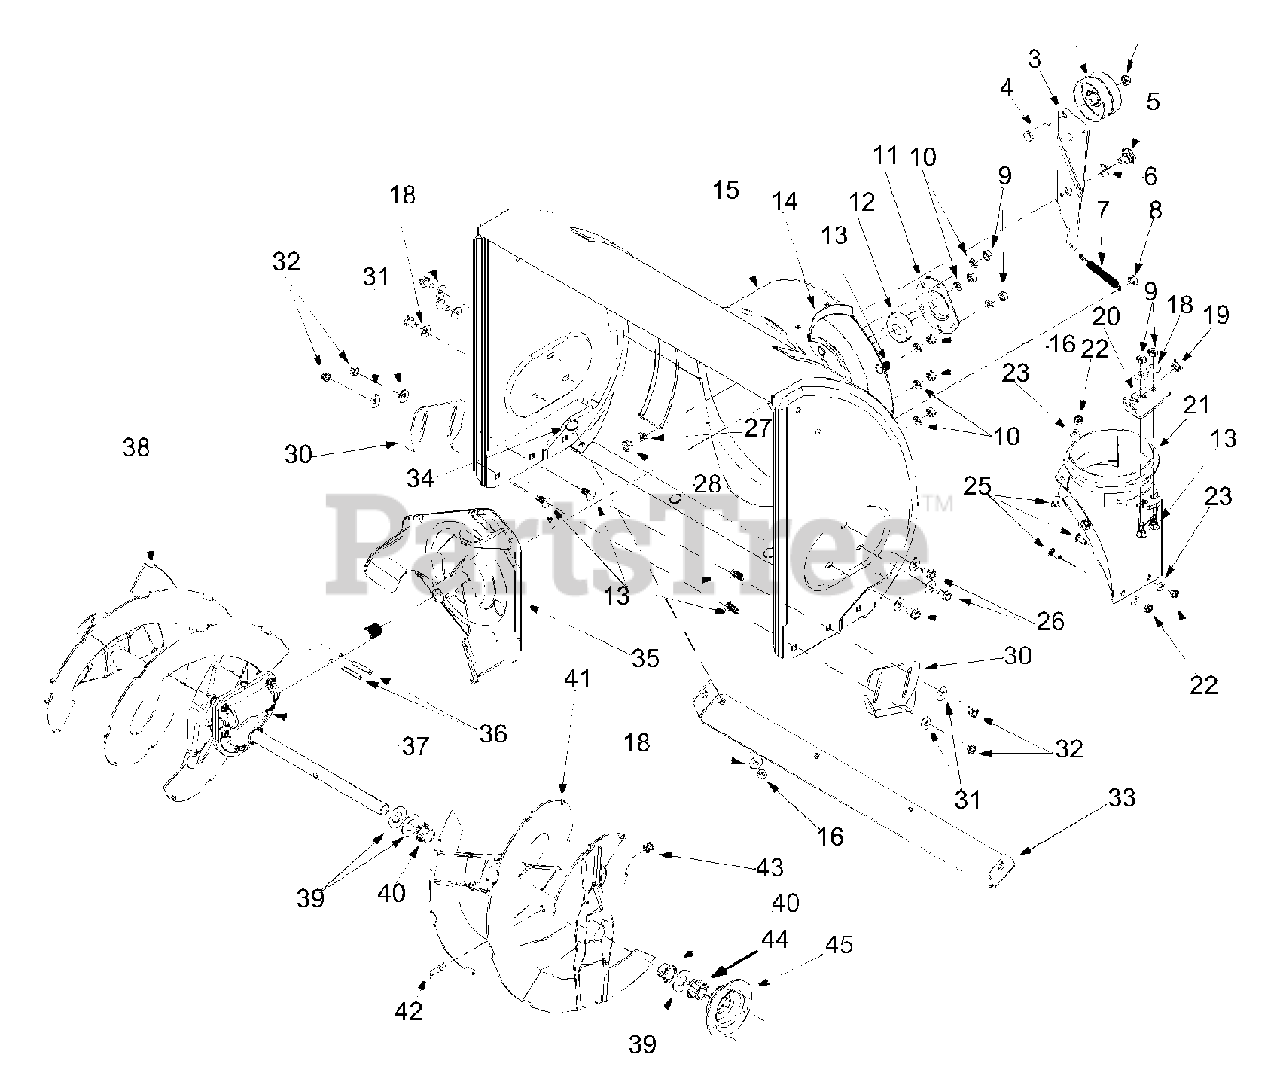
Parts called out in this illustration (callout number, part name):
1	Lock Jam Nut 3/8-24
2	Flat Idler
4	Hex Cap Screw 3/8-24 x 1.50
5	Shoulder Screw
6	Wave Washer
7	Extension Spring
8	Hex Nut 5/16-18
9	Hex Nut 5/16-18
10	Lock Washer 5/16
11	Housing
12	Ball Bearing
13	Carriage Bolt 5/16-18 x .75
18	Bell Washer
19	Bushing
21	Chute Adapter
22	Hex Lock Nut 1/4-20
23	Flat Washer
25	Carriage Screw 1/4-20 x .75
26	Hex Washer TT Screw 5/16-18
27	Lock Washer 3/8
28	Hex Nut 3/8-16
31	Bell Washer
32	Hex Nut 5/16-18
34	Carriage Bolt 5/16-18 x .62
37	24" Gear Assembly
39	Flat Washer
40	Flange Bushing
42	Shear Bolt 5/16-18 x 1.5
43	Lock Nut 5/16-18
44	Hex Flange Bearing
